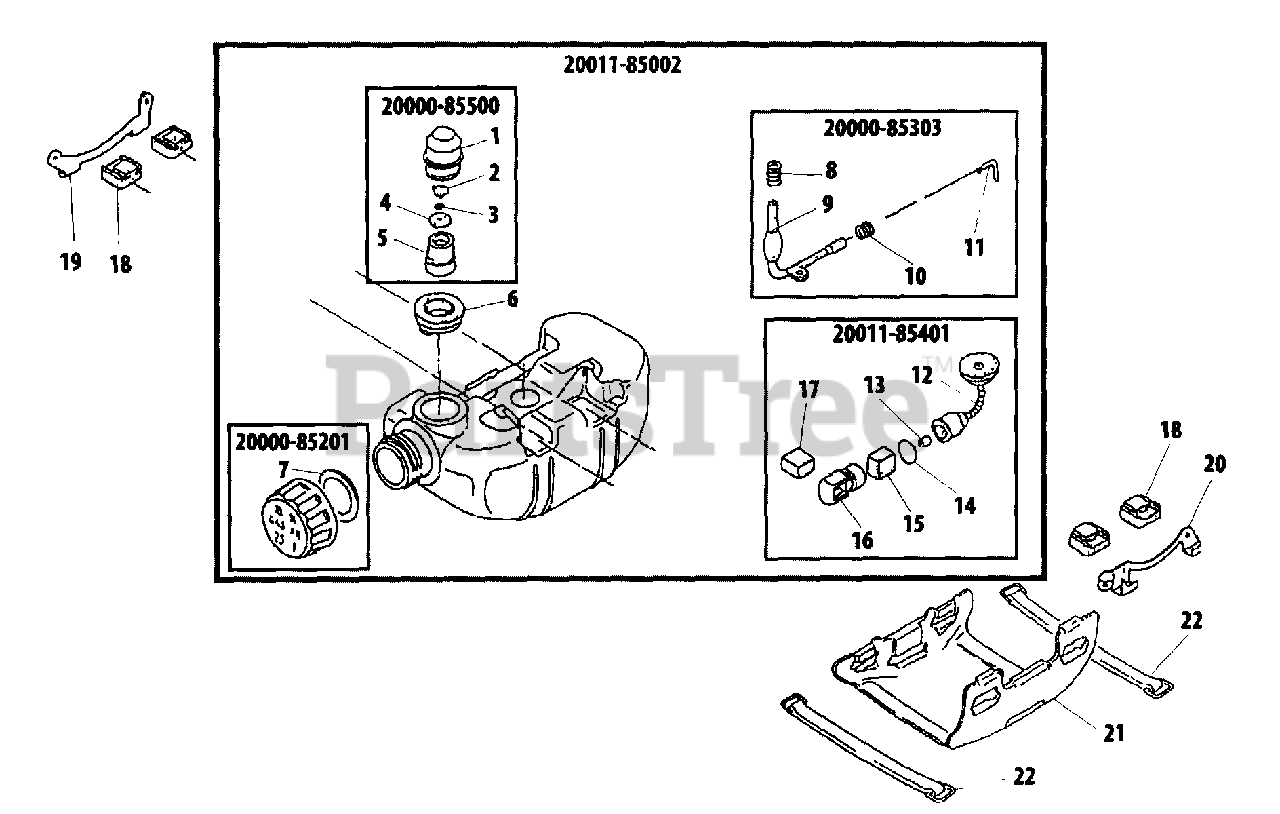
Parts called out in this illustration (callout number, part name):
1	CAP, BREATHER
2	VALVE, BREATHER
3	WASHER
4	RETAINER
5	HOLDER, VENT
6	GROMMET
7	GASKET, CAP
8	CLIP
9	CONNECTOR, PIPE
10	RING, RETAINING
11	CONNECTOR, PIPE
12	PICK-UP TUBE
13	VENT, FUEL TANK
14	CLIP
15	FILTER, FUEL - B
16	WEIGHT, FUEL FILTER
17	FILTER, FUEL - A
18	CUSHION
19	BRACKET - INNER
20	BRACKET - OUTER
21	GUARD, FUEL TANK
22	STRAP, FUEL TANK
20000-85201	CAP ASSY
20000-85303	FUEL PIPE ASSY
20000-85500	VENT, FUEL TANK
20011-85002	FUEL TANK ASSY
20011-85401	FUEL FILTER ASSY
